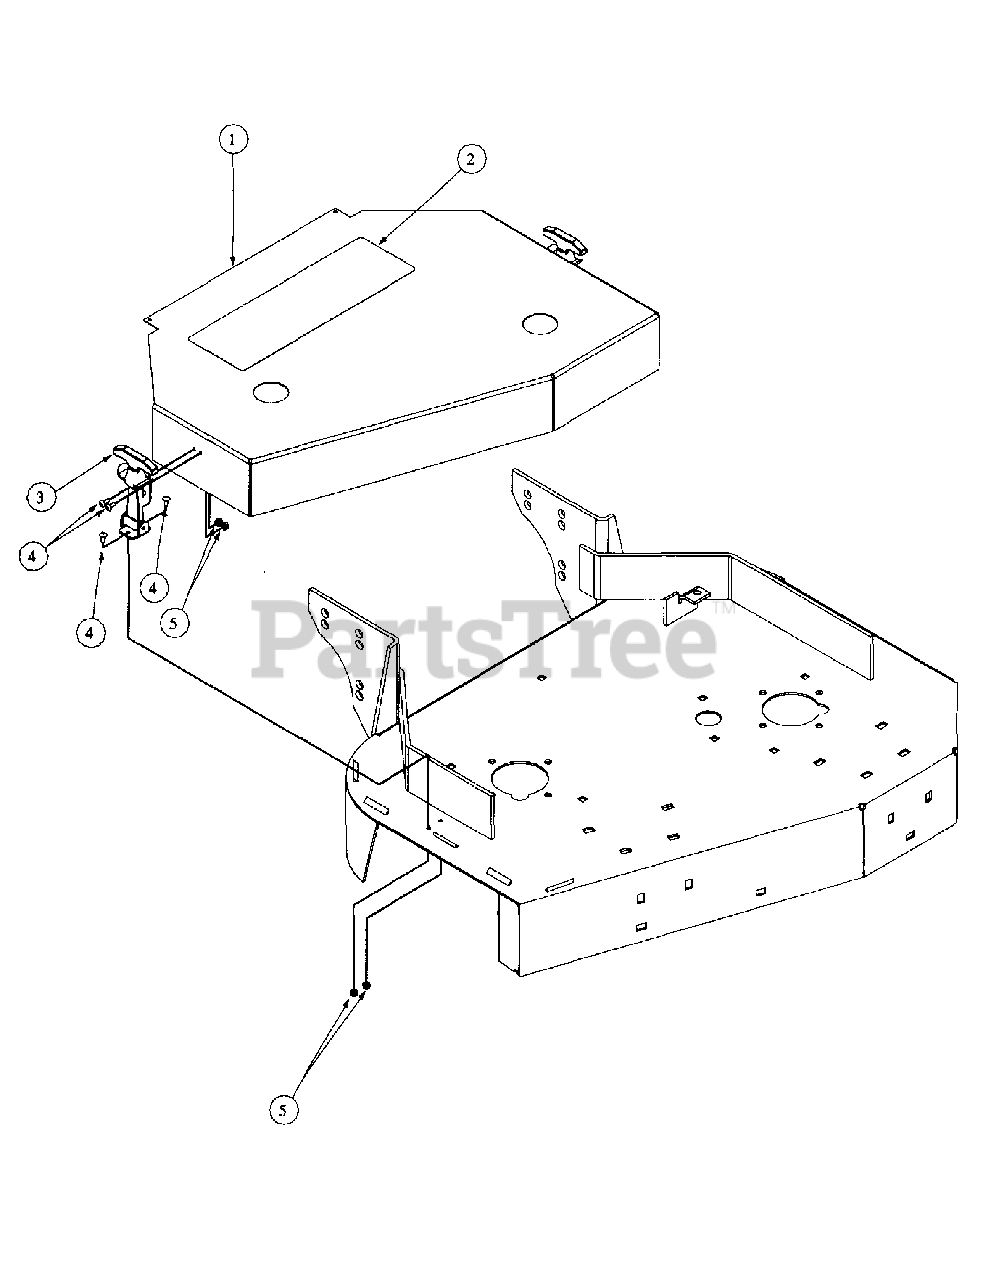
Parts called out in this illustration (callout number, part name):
1	Deck Cover, 32"
2	Decal, 32"
3	Rubber Hood Latch
4	Machine Screw, 10-24 x 1/2
5	Lock Nut, Nylon Insert, 10-24
